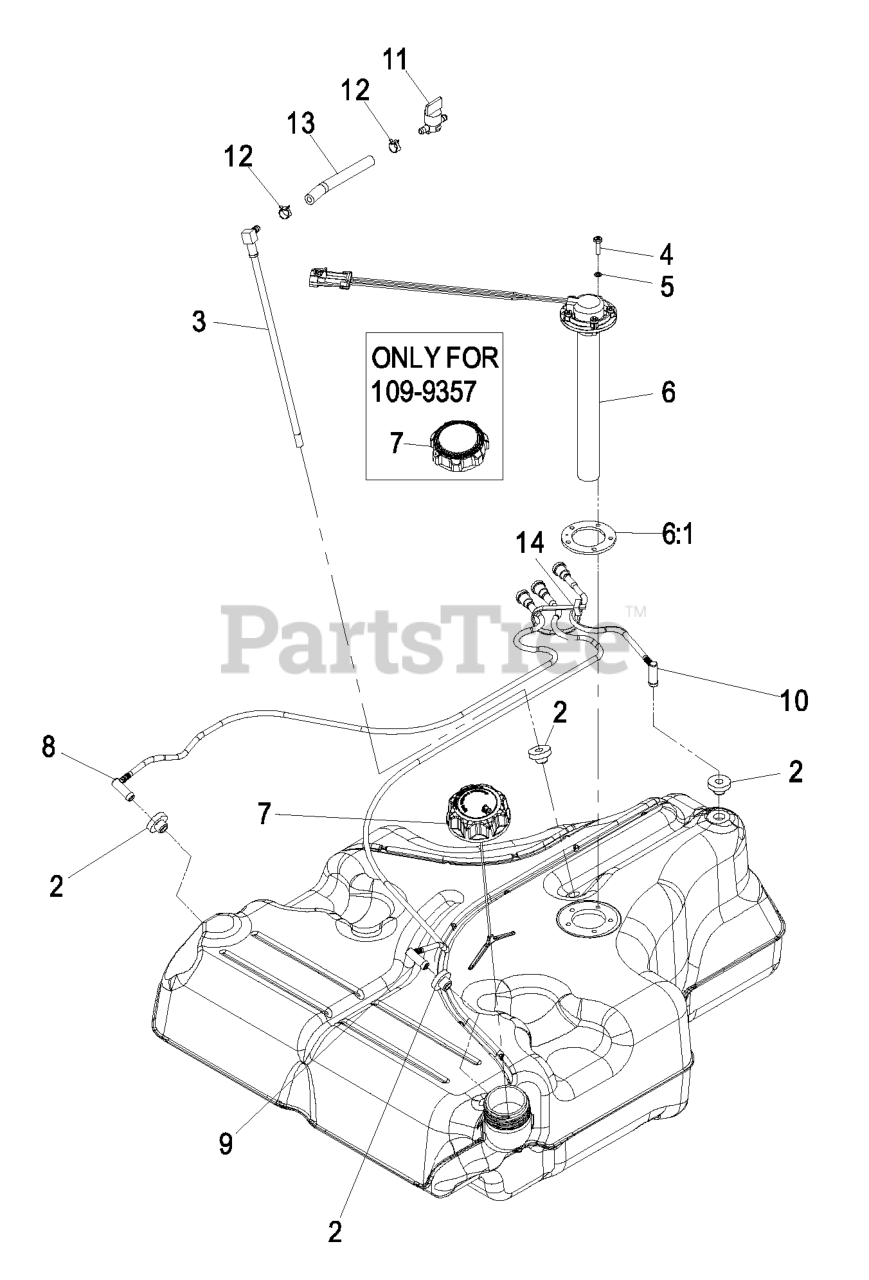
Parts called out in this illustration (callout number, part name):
2	BUSHING
3	FUEL LINE KIT (WITH GROMMET)
4	SCREW-PAN
5	WASHER-LOCK
6:1	GASKET-SENDER, FUEL
8	RH VENT LINE KIT (WITH GROMMET)
9	LH VENT LINE KIT (WITH GROMMET)
10	REAR VENT LINE KIT (WITH GROMMET)
11	VALVE-FUEL
12	CLAMP-HOSE
13	HOSE-FUEL
14	TIE-PLASTIC
